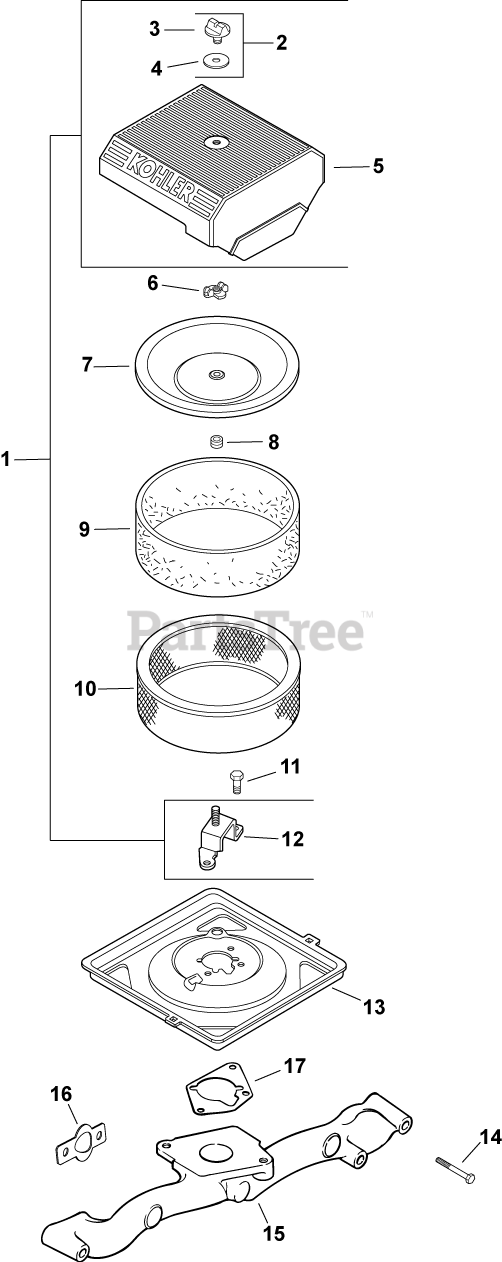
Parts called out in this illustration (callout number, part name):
1	KIT, AIR CLEANER COVER
2	KIT, KNOB W/SEAL
3	KNOB, COVER
5	COVER, AIR CLEANER
6	NUT, WING
7	COVER, INNER AIR CLEANER
8	SEAL, BREATHER
9	PRE-CLEANER (HIGH)
10	ELEMENT, AIR FILTER (HIGH) - Also available Retail Packaged 24 883 03-S1 Air Filter Kit
11	SCREW, FLG THD FRM M6X1.0X16
12	BRACKET, AIR CLEANER-USE 24 126 210-S
13	BASE, AIR CLEANER -USE 24 094 88-S
14	SCREW, FLG M6X1.0X55
15	MANIFOLD, METAL INTAKE
16	GASKET, INTAKE MANIFOLD USE 24 041 79-S
17	GASKET, AIR CLEANER BASE
